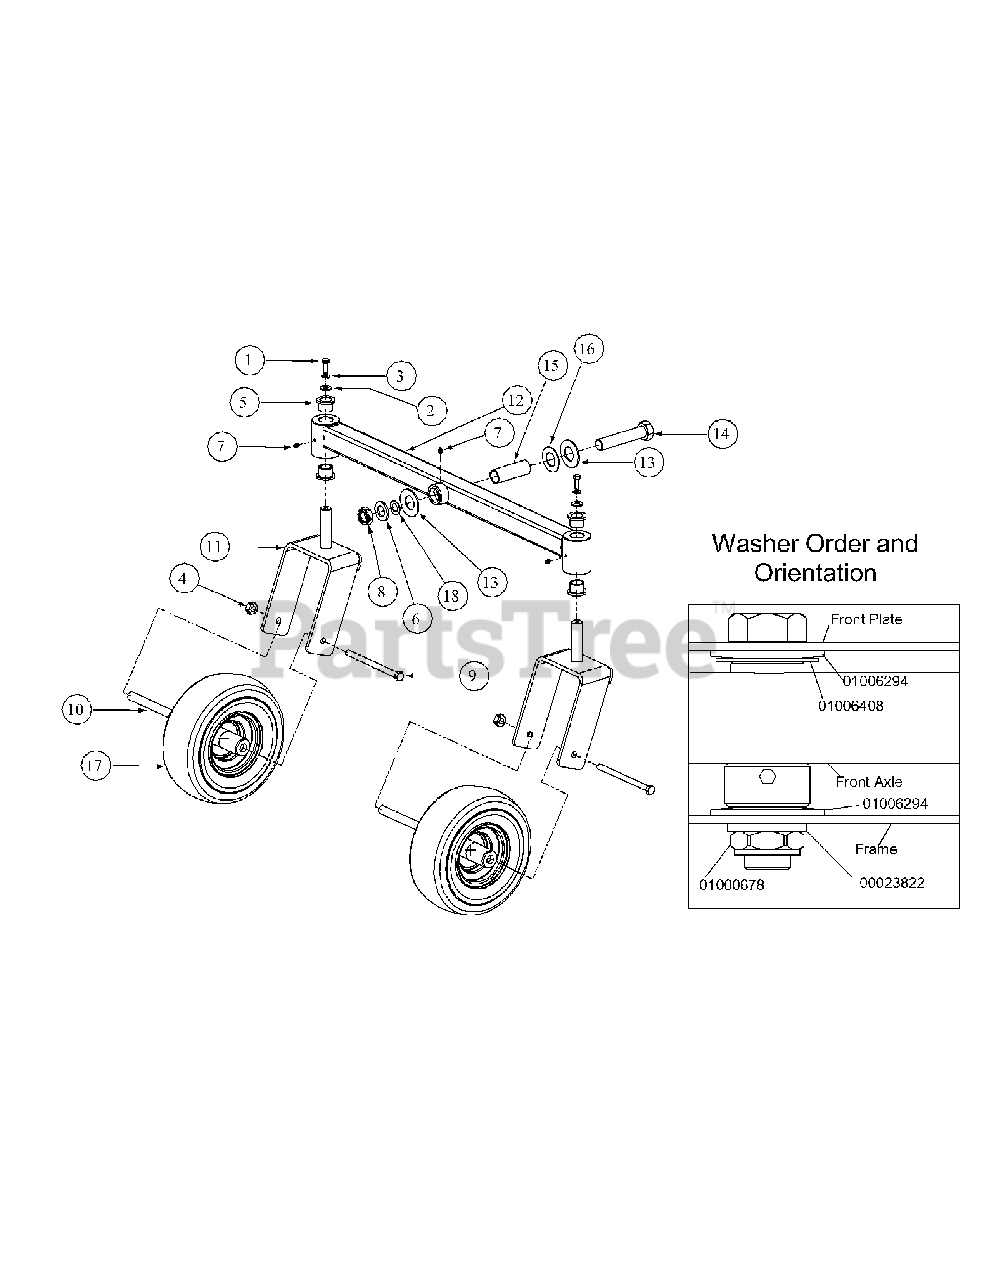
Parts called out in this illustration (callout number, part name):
1	Hex Cap Screw, 3/8-16, x 1
2	Flat Washer, .411 x 1.25 x 1.00
3	Lock Washer, 3/8
4	Center Lock Nut, 1/2-20
5	Flange Bearing, 1.013
6	Special Washer
7	Grease Fitting, 1/4-28 x 3/16
8	Jam Lock Nut, 1.0-14
9	Hex Cap Screw, 1/2-20 x 7.00
10	Spacer, .51 ID x .75 OD x 5.83 Lg
11	Caster Wheel Bracket Assembly
12	Narrow Front Axle Assembly
13	Belle Washer, 1.25 ID x 2.500 OD x .1
14	Hex Cap Screw, 1-14 x 5.0
15	Spacer, 1.005 ID x 1.25 OD x 3.6
16	Flat Washer, 1.25 ID x 2.25 OD x .075
17	Wheel Assembly, 11 x 4-5.00
18	Retainer Extension, Self Locking
